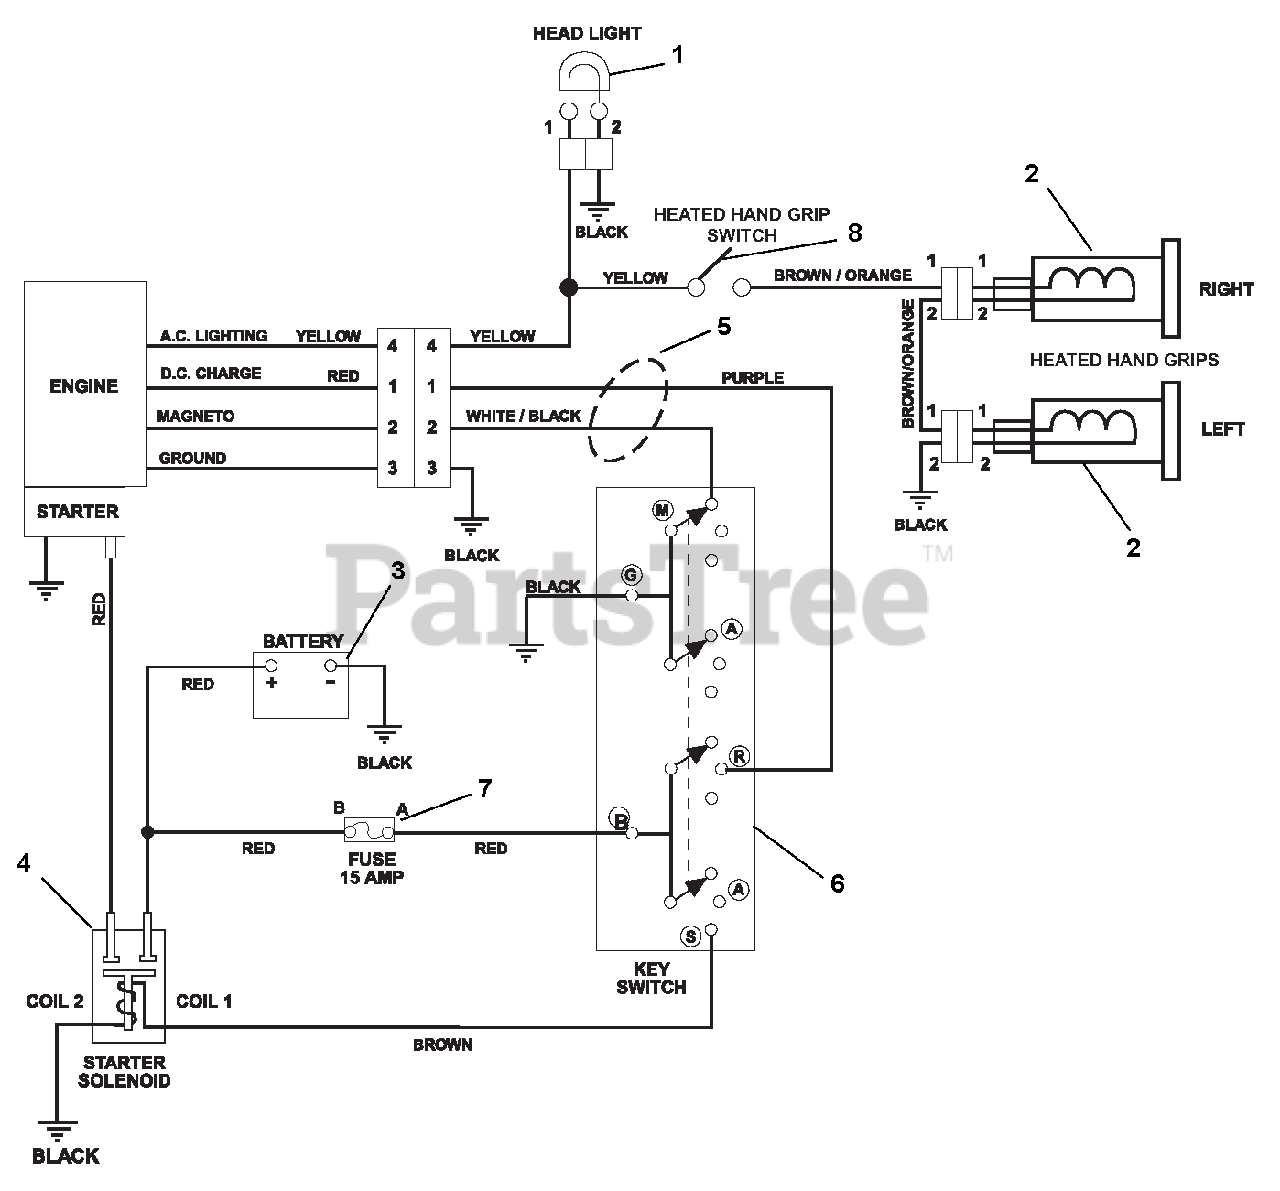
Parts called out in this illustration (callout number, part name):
1	HEADLIGHT ASSY, HALOGEN 20W
2	HEATED GRIP, MAGURA
4	SOLENOID
5	HARNESS, 12V
6	SWITCH ASSEMBLY
7	FUSE, 15 AMP.
8	SWITCH, ON/OFF
